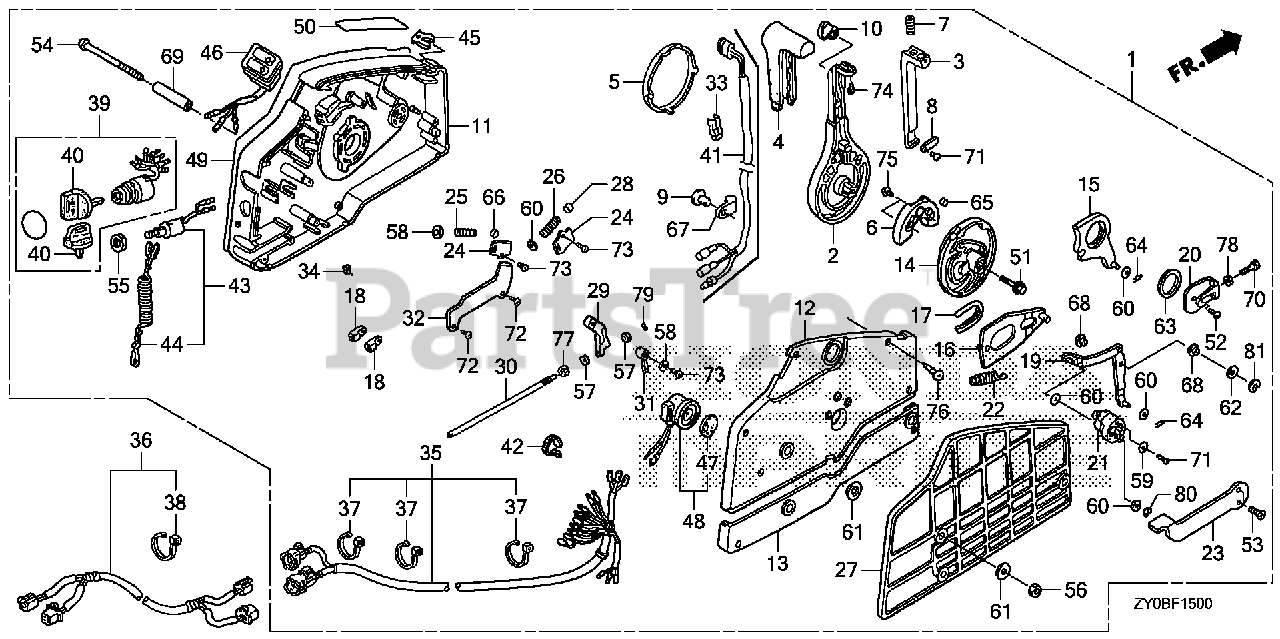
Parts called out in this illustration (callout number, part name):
1	S/R SW 2 LIGH POW TL
1	BOX ASSY., REMOTE CONTROL (HI-LEX)(PT)
2	HANDLE, REMOTE CONTROL
3	LEVER, HANDLE LOCK
4	GRIP, REMOTE CONTROL HANDLE
5	CAP, HANDLE
6	BLOCK, NEUTRAL LOCK
7	SPRING, REMOTE CONTROL HANDLE
8	PLATE, LEVER SETTING
9	CLAMP, HARNESS
11	HOUSING, REMOTE CONTROL BOX (A)
12	HOUSING, REMOTE CONTROL BOX (B)
13	HOUSING, REMOTE CONTROL BOX (C )
14	WHEEL, CONTROL
15	ARM, SHIFT LINK
16	PLATE, SLIDING
17	COLLAR, SLIDING PLATE
18	PIVOT, SHIFT
19	ARM, LINK JOINT
20	BRACKET, LINK JOINT
21	WHEEL, ACCELERATOR
22	SPRING, ACCELERATOR WHEEL
23	LEVER, IDLE
24	PLATE, SPRING SETTING
25	SPRING, SHIFT CLICK
26	SPRING, CHOKE RETURN
27	SPACER, REMOTE CONTROL BOX
28	SPACER, CLICK SPRING
29	BLOCK, THROTTLE FRICTION
30	BOLT, FRICTION
31	SPACER, NEUTRAL SWITCH
32	CLAMP, POWER TILT CORD
33	PIPE, HARNESS GUIDE
34	SPACER, CABLE CLAMP
35	CABLE ASSY. B, REMOTE CONTROL (4P+6P)
36	CABLE ASSY., REMOTE CONTROL EXTENSION (4P+6P)
37	TIE, CABLE (NATURAL 2.4X92) Use up to Frame SN 1300359.
38	TIE, CABLE (NATURAL 2.4X92) Use up to Frame SN 1300359.
39	SWITCH ASSY., COMBINATION DUAL QTY = (2) (SINGLE)
39	SWITCH ASSY., COMBINATION (SINGLE) (DUAL)
40	KEY ASSY., COMBINATION SWITCH (35100-ZV5-003 ONLY) DUAL QTY = (4) (SINGLE)
41	SWITCH ASSY., POWER TRIM-TILT
42	BAND (BLACK 3.5X140)
43	SWITCH ASSY., EMERGENCY STOP
44	WIRE, EMERGENCY (SINGLE) (DUAL)
45	CLIP, EMERGENCY LOCK
46	LAMP ASSY., INDICATOR
47	PLATE, TURN SIGNAL BUZZER DUAL QTY = (2) (SINGLE)
48	BUZZER, WARNING DUAL QTY = (2) (SINGLE)
49	PLATE, REMOTE CONTROL (CAUTION=SILVER)
49	PLATE, REMOTE CONTROL (COUTION COLOR=RED & YELLOW)
50	MARK, FAST IDLE
51	BOLT, FLANGE (8X35) Use from Frame SN 4800713.
52	SCREW, PAN (6X10)
53	SCREW, FLAT (5X12) Use from Frame SN 4800713.
54	SCREW (6X95)
55	NUT, HEX. (16MM) DUAL QTY = (2) (SINGLE)
56	NUT, HEX. (6MM)
57	WASHER, PLAIN (4MM) Use from Frame SN 4800713.
58	WASHER, PLAIN (5MM)
59	WASHER, PLAIN (5MM)
60	WASHER, PLAIN (6MM) Use from Frame SN 4800713.
61	WASHER (6MM)
62	WASHER, PLAIN (8MM) Use from Frame SN 4800713.
63	WASHER (28MM)
64	PIN, LOCK (6MM)
65	PIN (6X6)
66	ROLLER, CLICK
67	CLIP, WIRE HARNESS (6.3MM)
68	COLLAR, LINK JOINT
69	COLLAR, DISTANCE (6X10X43.5)
70	BOLT, HEX. (5X16)
71	SCREW, PAN (5X10)
72	SCREW, TAPPING (5X8) (FOR SILVER MUFFLER)
73	SCREW, TAPPING (5X10)
74	SCREW, TAPPING (5X12)
75	SCREW, TAPPING (6X16)
76	SCREW, TAPPING (5X25)
77	NUT, HEX. (6MM)
78	NUT, HEX. (5MM)
79	E-RING (3MM)
80	E-RING (4MM)
81	E-RING (7MM)
